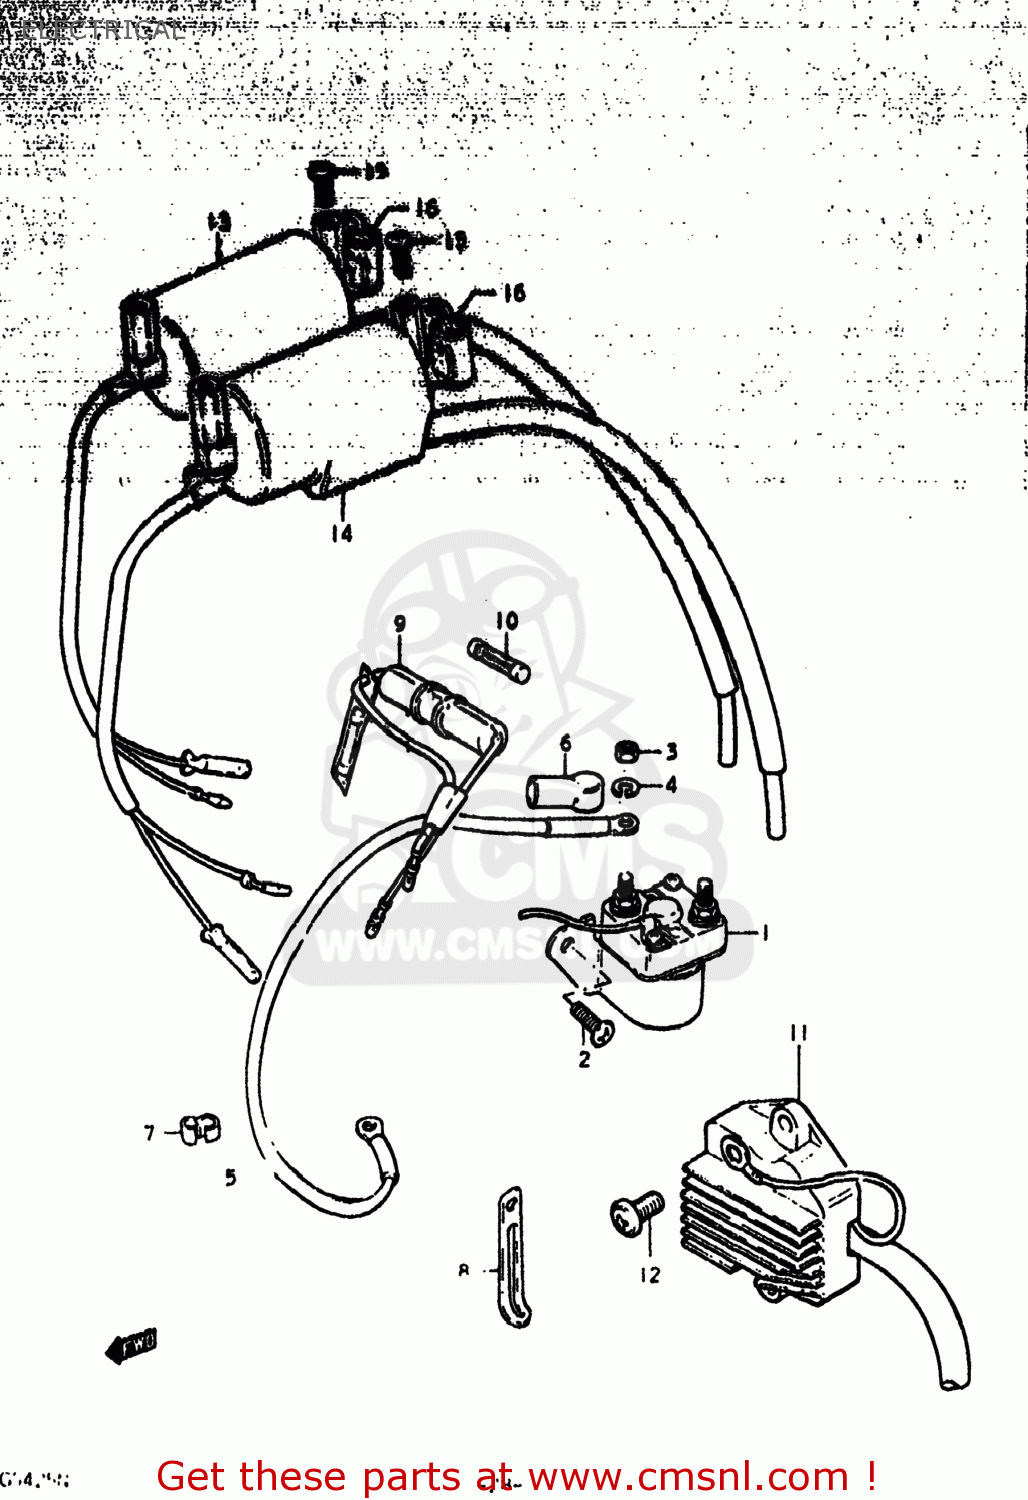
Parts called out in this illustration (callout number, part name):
1	RELAY ASSY,STARTING MOTOR
2	SCREW
3	NUT 6MM
4	LOCK WASHER
5	WIRE,STARTER MOTOR LEAD
6	CAP,STARTER RELAY
7	CLIP
8	CLAMP L:35
9	BOX ASSEMBLY,FUSE
10	FUSE(15A)
11	RECTIFIER ASSEMBLY
12	SCREW
13	COIL ASSEMBLY,IGNITION
14	COIL ASSEMBLY,IGNITION
15	SCREW
16	CONDENSER
